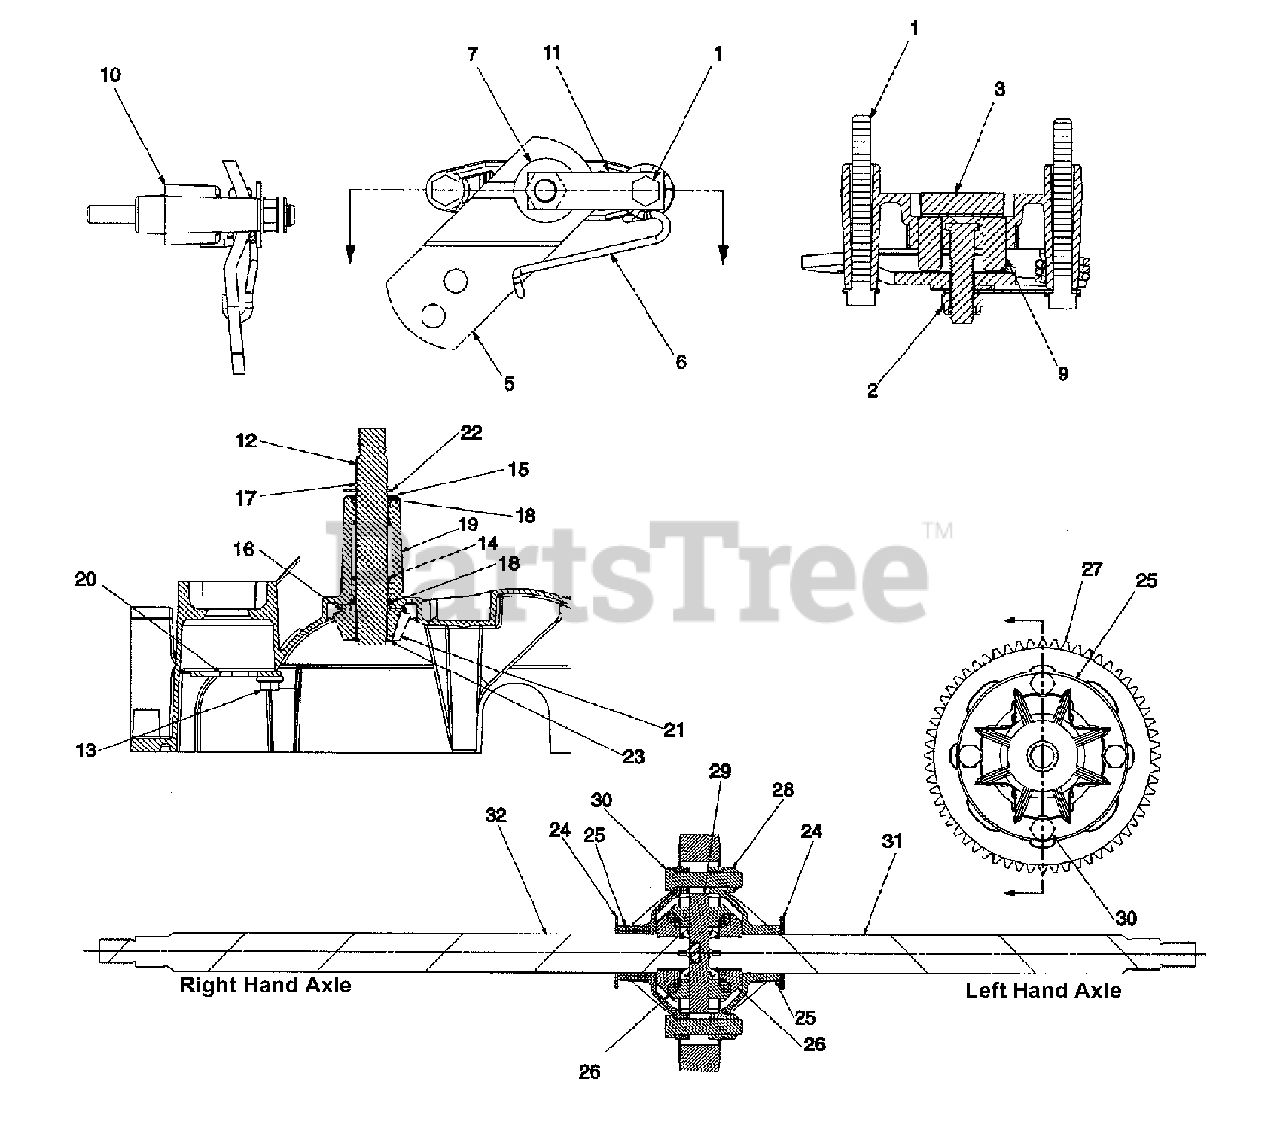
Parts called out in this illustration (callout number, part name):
1	Hex Washer Hd. Scr. 1/4-20 x 2.37
2	Nylon L-Nut 5/16-24 Thd.
3	Brake Puck
5	Brake Arm
6	Torsion Spring
7	Flat Washer .343" I.D. x .88" O.D.
9	Brake Pin
10	Brake Yoke
11	Brake Anti Rotation Brkt.
12	Input Shaft
13	Hex Washer AB-Tap Scr.1/4-14 x 1"
14	Needle Brg. .625" I.D.
15	Flat Washer 5/8" I.D. x 1" O.D.
16	Thrust Washer .635" I.D. x 1.25" O.D
17	Wire Ring
19	Upper Housing
20	Lockout Plate
21	Bevel Gear
22	Retainer Ring
23	Retainer Ring
24	Flat Washer 1" I.D. x 1.8" O.D.
25	Differential Housing
26	10T Miter Gear
27	Spur Gear 60T
28	Hex L-Nut 3/8-24 Thd.
29	Cross Shaft
30	Hex Bolt 3/8-24 x 2"
31	Axle Assembly LH
32	Axle Assembly RH
